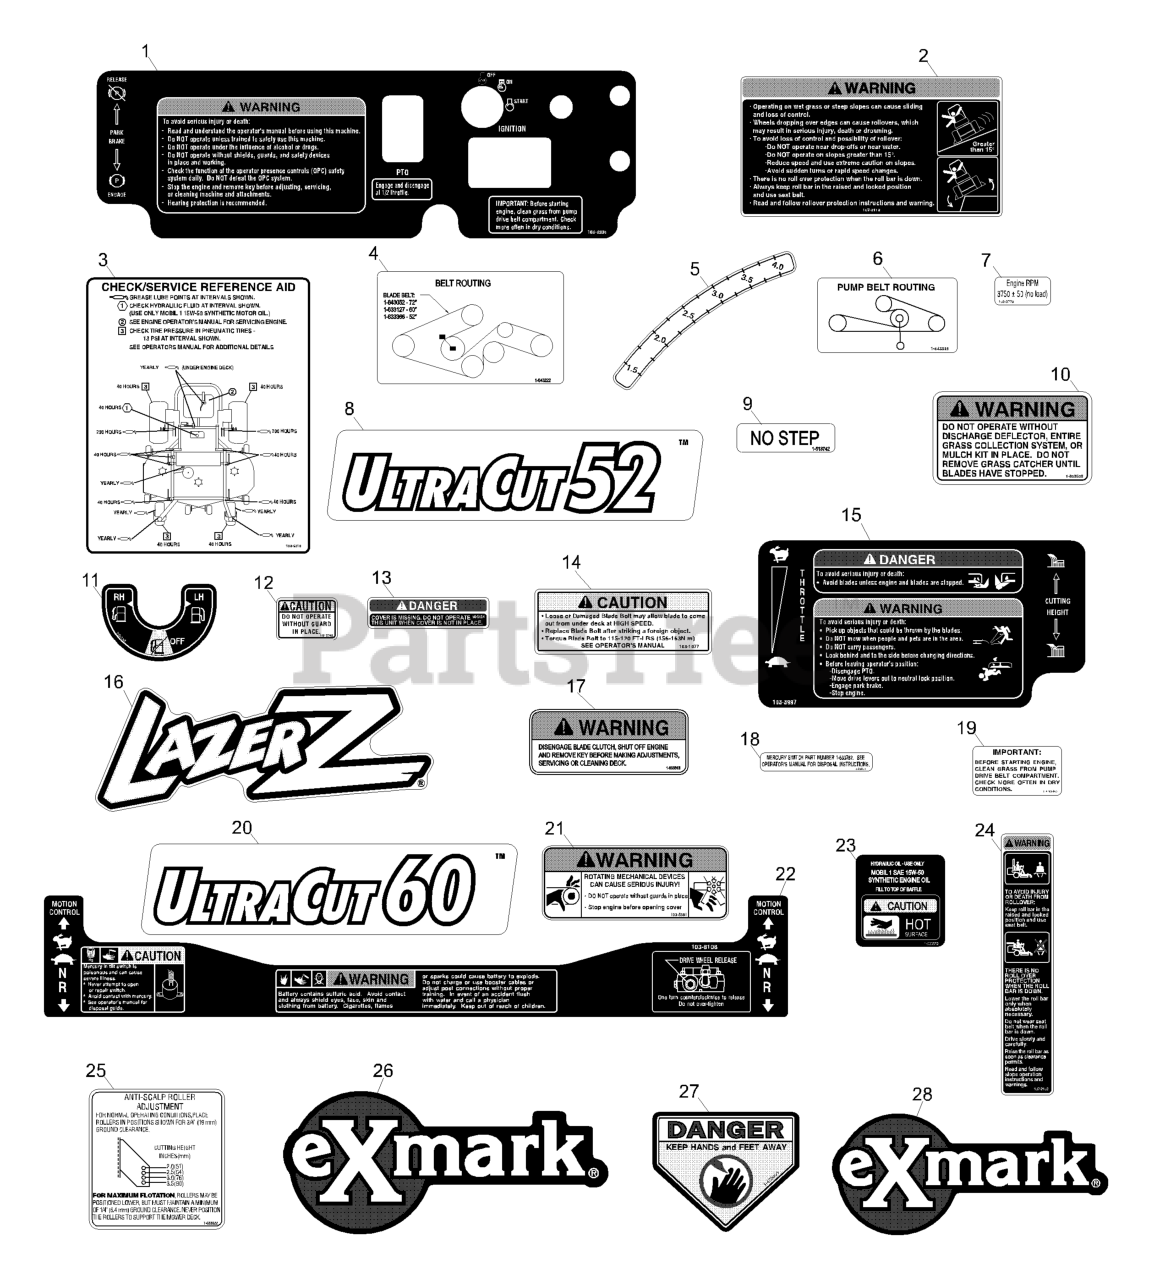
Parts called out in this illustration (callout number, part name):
1	DECAL,CONSOLE
2	DECAL-WARNING
3	DECAL,CHECK SERVICE LZ
4	DECAL,BELT ROUTING
6	DECAL-ROUTING, BELT
8	DECAL,ULTRACUT 52
9	DECAL,NO STEP
10	DECAL-WARNING, DISCHARGE
11	DECAL-VALVE, FUEL
12	DECAL-GUARD
13	DECAL-COVER, MISSING
14	DECAL,BOLT TORQUE
16	DECAL,LAZER MODEL
17	DECAL,WARNING
18	DECAL-SWITCH, MERCURY
19	DECAL-IMPORTANT
20	DECAL,ULTRACUT 60
21	DECAL-DEVICES, ROTATING
22	DECAL, TOP CONSOLE
24	DECAL-WARNING, FOLDING RO
25	DECAL,ANTISCALP
26	DECAL,EXMARK LOGO
27	DECAL-DANGER
28	DECAL,EXMARK LOGO
